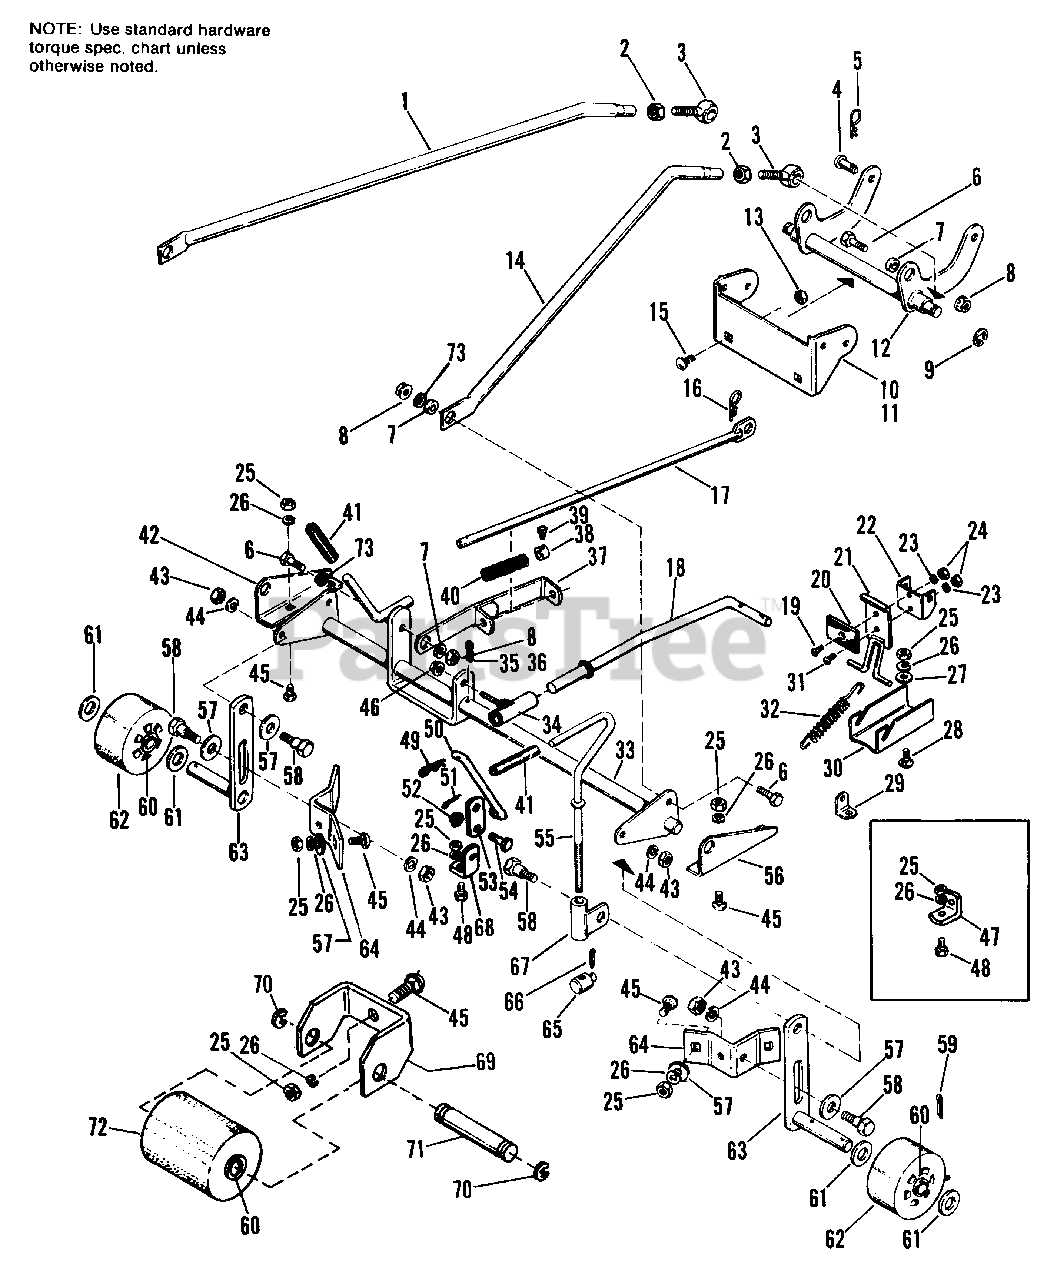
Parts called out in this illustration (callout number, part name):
1	ARM, Adjusting, L.H.
2	LOCKNUT, Jam, 1/2-20
5	CLIP, Spring
6	CAPSCREW, Hex Hd., 3/8-16 x 1
8	NUT, Hex, Flange, 3/8-16
9	RING, Retaining
10	BRACKET, Mower, Front
11	BRACKET, Mower, Front
12	ARM ASSY., Rocker
13	NUT, Hex, Flange, 5/16-18
14	ARM, Adjusting, R.H.
15	SCREW, Hex, Whizlock, 5/16-18 x 3/4
16	CLIP, Spring
17	ROD ASSY., Clutch
18	ROD, Brake
19	SCREW, Flat Hd., Mach., #10-24 x 1/2
20	SHEAVE, Brake
21	SUPPORT ASSY., Brake
22	ANCHOR, Rod, Brake
23	LOCKWASHER, #10
24	NUT, Hex, Full, #10-24
25	NUT, Hex, Full, 5/16-18
26	LOCKWASHER, 5/16
27	WASHER, Plain, 5/16
28	BOLT, Carriage, 5/16-18 x 1
29	ANCHOR, Spring
30	BRACKET, Pivot
31	SCREW, Rd. Hd., Mach., #10-24 x 1/2
33	ARM ASSY., Control
34	GUIDE ASSY., Rod
35	PIN, Roll, 1/8 x 1
36	PIN, Cotter, 1/8 x 1-1/4
37	GUIDE ASSY., Rod
38	COLLAR, Set
39	SETSCREW, 1/4-20 x 3/8
41	GRIP, Handle
42	BRACKET, Pivot, L.H.
43	NUT, Hex, Full, 3/8-16
44	LOCKWASHER, 3/8
45	BOLT, Carriage, 5/16-18 x 5/8 (Qty. 8 on 990998 & 991000)
46	LOCKNUT, Hex, 3/8-16
47	BRACKET
48	CAPSCREW, Hex Hd., 5/16-18 x 5/8
49	CLIP, Hair Pin
50	ROD
51	PIN, Cotter, 3/32 x 5/8
52	LOCKNUT, Hex, 5/16-18
53	LINK
54	CAPSCREW, Hex Hd., 5/16-18 x 3/4
56	BRACKET, Pivot, R.H.
57	WASHER, Plain, 7/16
58	BOLT, Shoulder, 3/8-16 X 1.34
59	PIN, Cotter, 3/16 x 1
61	WASHER, Plain, 5/8
62	ROLLER ASSY.
63	SUPPORT ASSY., Roller
64	SUPPORT, Bracket, Roller
66	PIN, Cotter, 3/32 x 1
67	GUIDE ASSY., Rod
69	BRACKET, Center Roller
70	RING, Snap
72	ROLLER ASSY.
73	WASHER, Plain, 3/8
